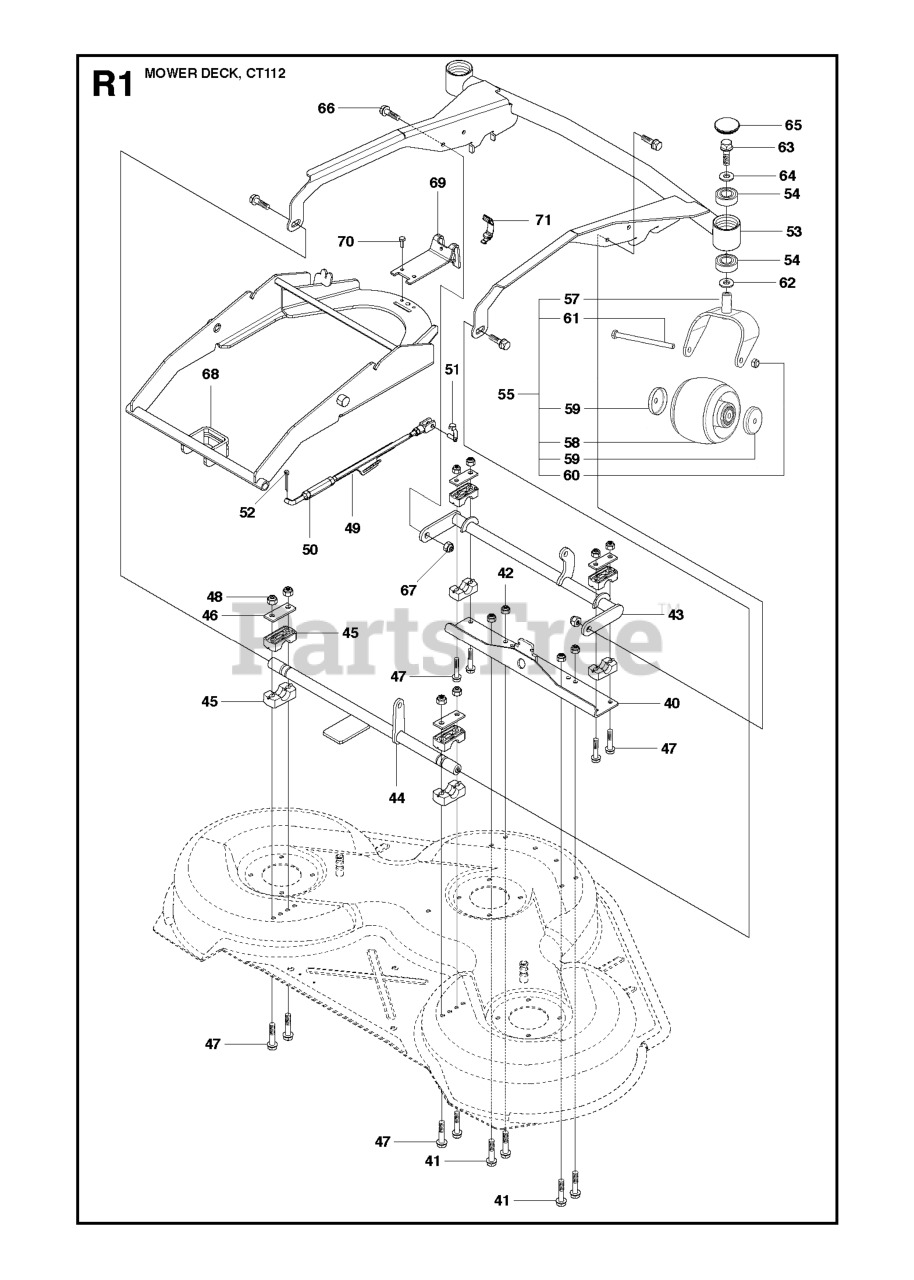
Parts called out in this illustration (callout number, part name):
42	LOCKNUT M8
48	LOCKNUT M8
50	PARALLEL ROD
54	BALL BEARING 6004-2RS1
65	HUB CAP PIVOT WHEEL
67	LOCKNUT M8
70	SCREW
71	CLIP GRAY
